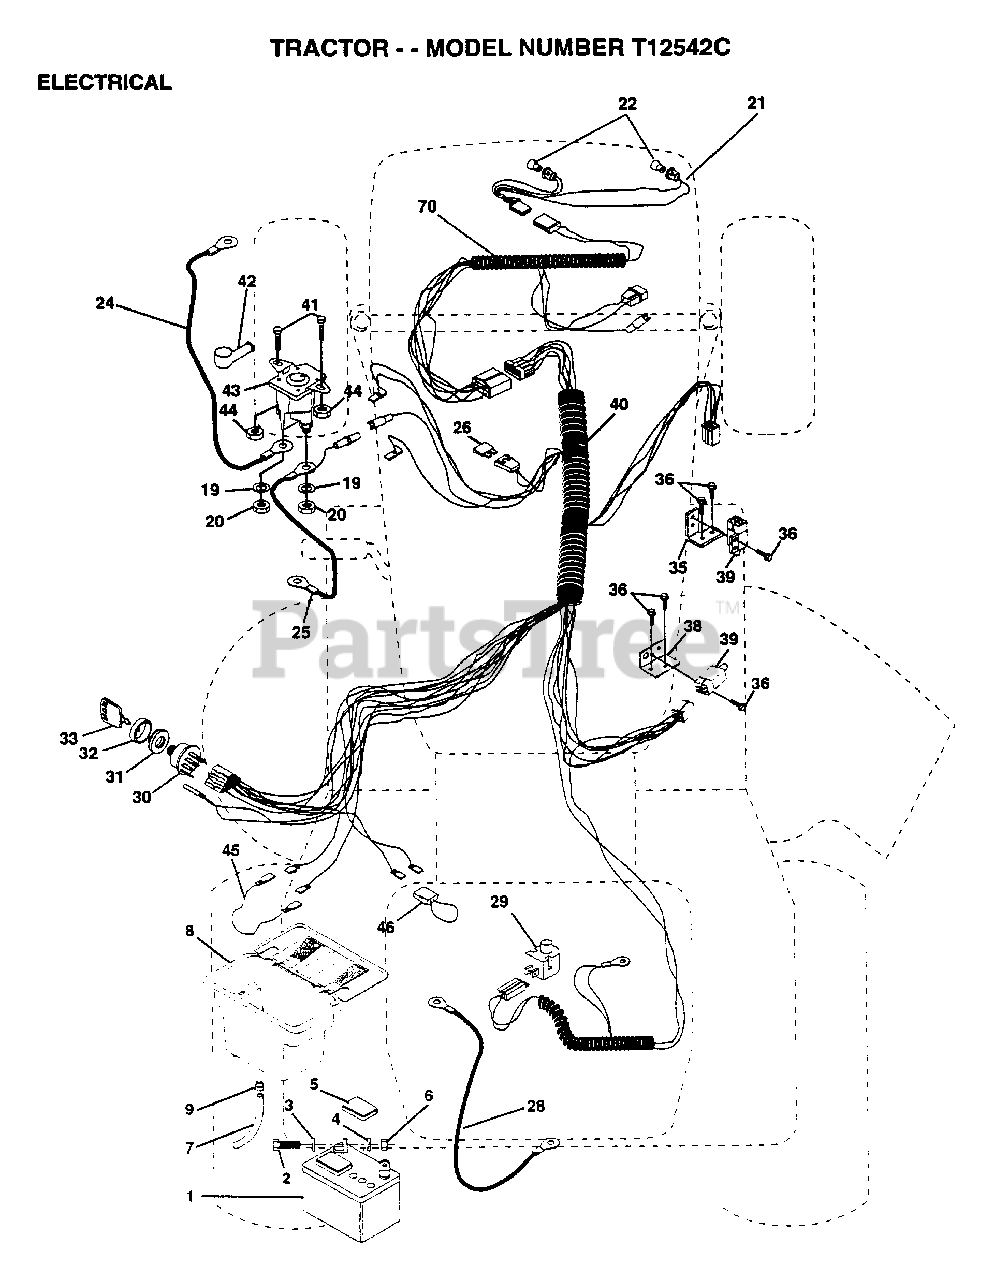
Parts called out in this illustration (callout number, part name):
2	BOLT LT
3	WASHER
4	LOCKWASHER
5	"CAP,BATTERY "
7	TUBE T
9	HOSE CLAMP T
20	NUT
21	"HARNESS,LIGHT SOC"
22	HEADLAMP BULB
24	"CABLE T, BATTERY"
25	CABLE.BTRY.6GA.RD
26	FUSE HYT
28	CABLE T
29	SWITCH SEAT
30	SWITCH IGN 4POS
31	NUT IGNITION
32	COVER KEY SWITCH
33	KEY
35	BRACKET LT
36	SCREW
38	BRACKET SWITCH IN
39	SWITCH INTERLOCKT
41	BOLT.HX.1/4-20
44	NUT
45	ADAPTER AMMETER
46	PROTECTION LOOP
70	HARNESS.ENGINE
